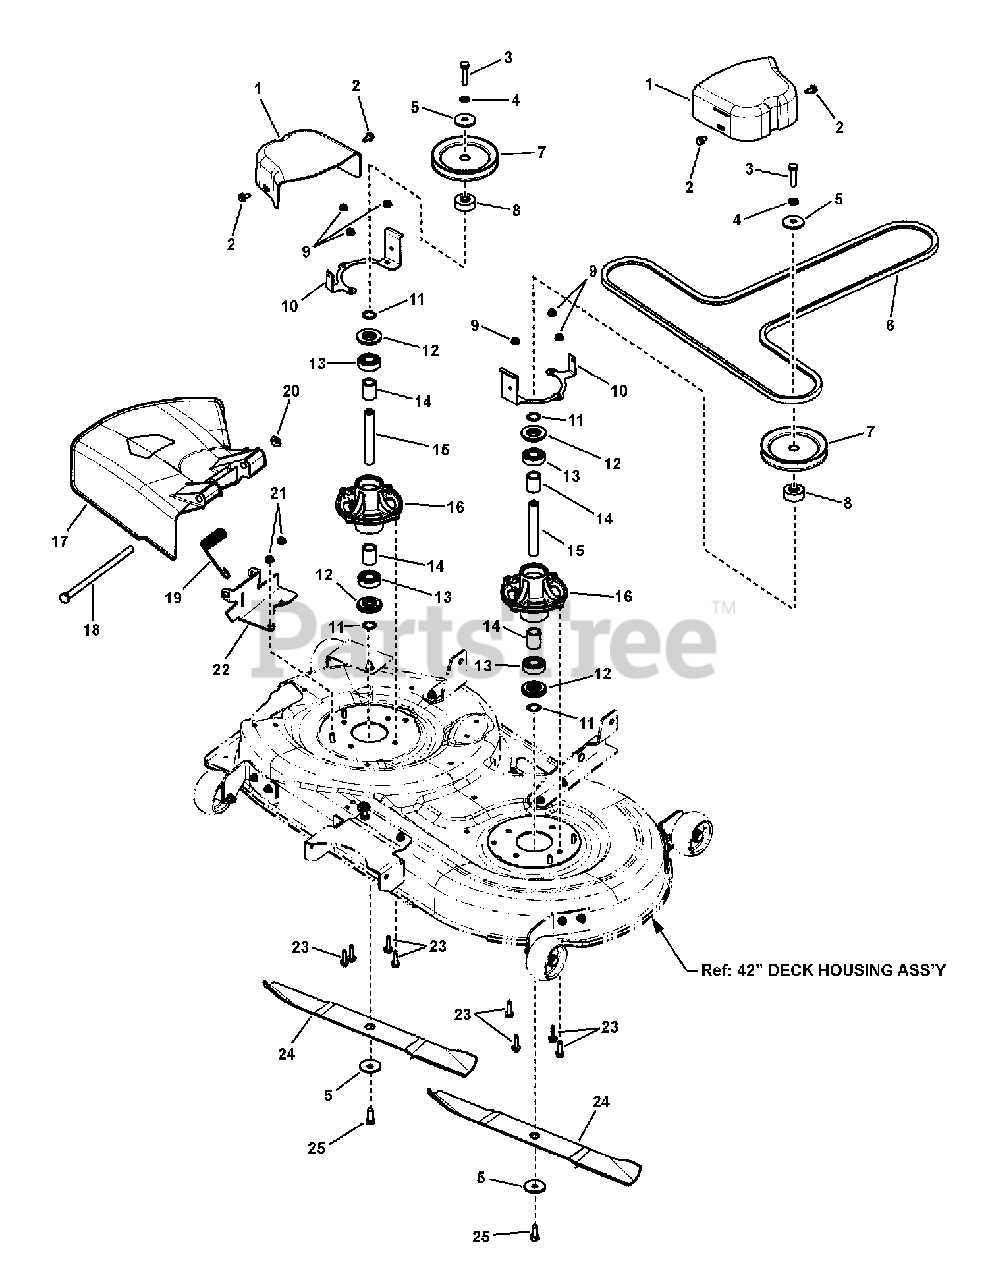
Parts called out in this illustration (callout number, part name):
1	BELT COVER, RH, HD Polypropolene, Black
2	SCREW, 5/16-18 x 5/8" Hex Washer Self-Tap, Black
3	SCREW, 7/16-14 x 1-3/4" Hex Head Cap, GR 5, Black
4	LOCKWASHER, .438, Spring, Black
5	WASHER, .475 ID x 1.75 OD x .156 Thick Spring, Black
6	V-BELT, HA 118.00 LG A-Wedge Aramid
7	PULLEY, V Deep Groove
8	SPACER, Pulley, Yellow Zinc
9	NUT, 5/16-18 Hex Flange Lock, Small - Black
10	BRACKET, Belt Cover
11	RING, Self Locking
12	SHIELD, Arbor, 2.050 OD
13	BALL BEARING, 20 MM
14	SPACER, Bearing Powdered Metal
15	SHAFT, Spindle 20MM Dia. 134.60 MM Long
16	HOUSING, Spindle, Cast Aluminum (Machined) w/Grease Fitting
17	SIDE CHUTE, Discharge
18	ROD, Pivot, Chute, Discharge
19	SPRING, Torsion, Side Discharge
20	PUSH NUT, for .500 Dia Stud, Capped, Black
21	NUT, 5/16-18 Hex Flange Lock, Large, Black
22	BRACKET, Hinge
23	SCREW, 5/16-18 x 1-1/4" Hex Washer Self-Tap
24	BLADE, 21.16"
25	SCREW, 7/16-14 x 1" Hex Head Cap, GR 5, Black
